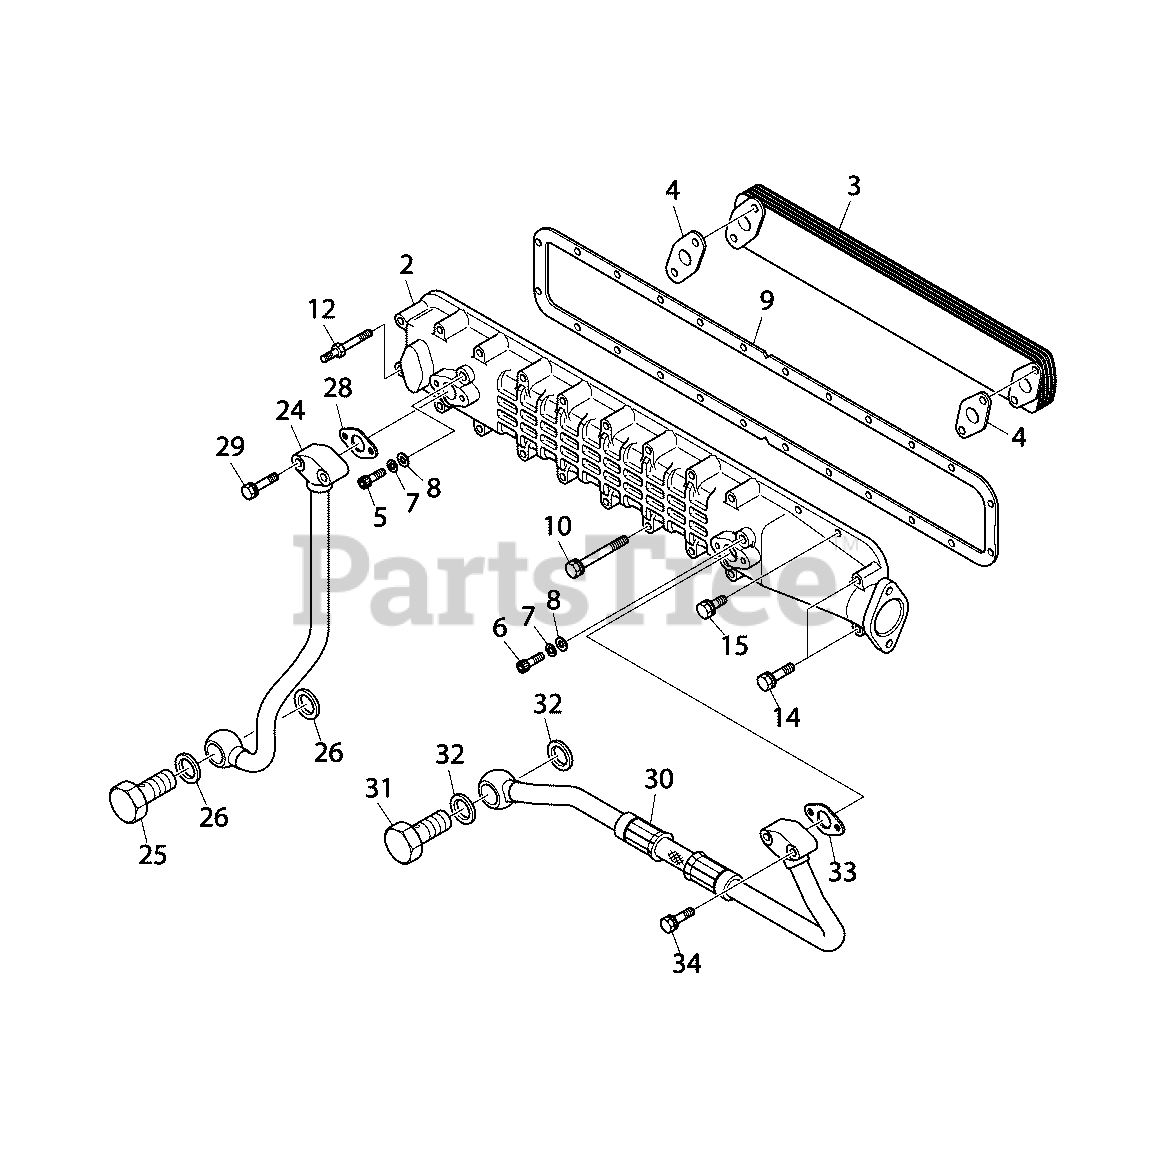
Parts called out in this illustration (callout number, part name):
1	* COOLER, OIL
2	* HOUSING,O/COOLER
3	* ELEMENT
4	GASKET, O/COVER
5	* BOLT
6	* BOLT
7	* WASHER, SPRING
8	* WASHER
9	GASKET, W/CHAMBER
10	* BOLT
12	* BLOCK, ENGINE
14	* BOLT
15	* BOLT
24	* PIPE, OIL
25	* SCREW, SCREEN
26	* SEAL, RING
28	GASKET, OIL PIPE
29	* BOLT
30	* PIPE, OIL
31	* SCREW, SCREEN
32	* SEAL, RING
33	GASKET, OIL PIPE
34	* BOLT
